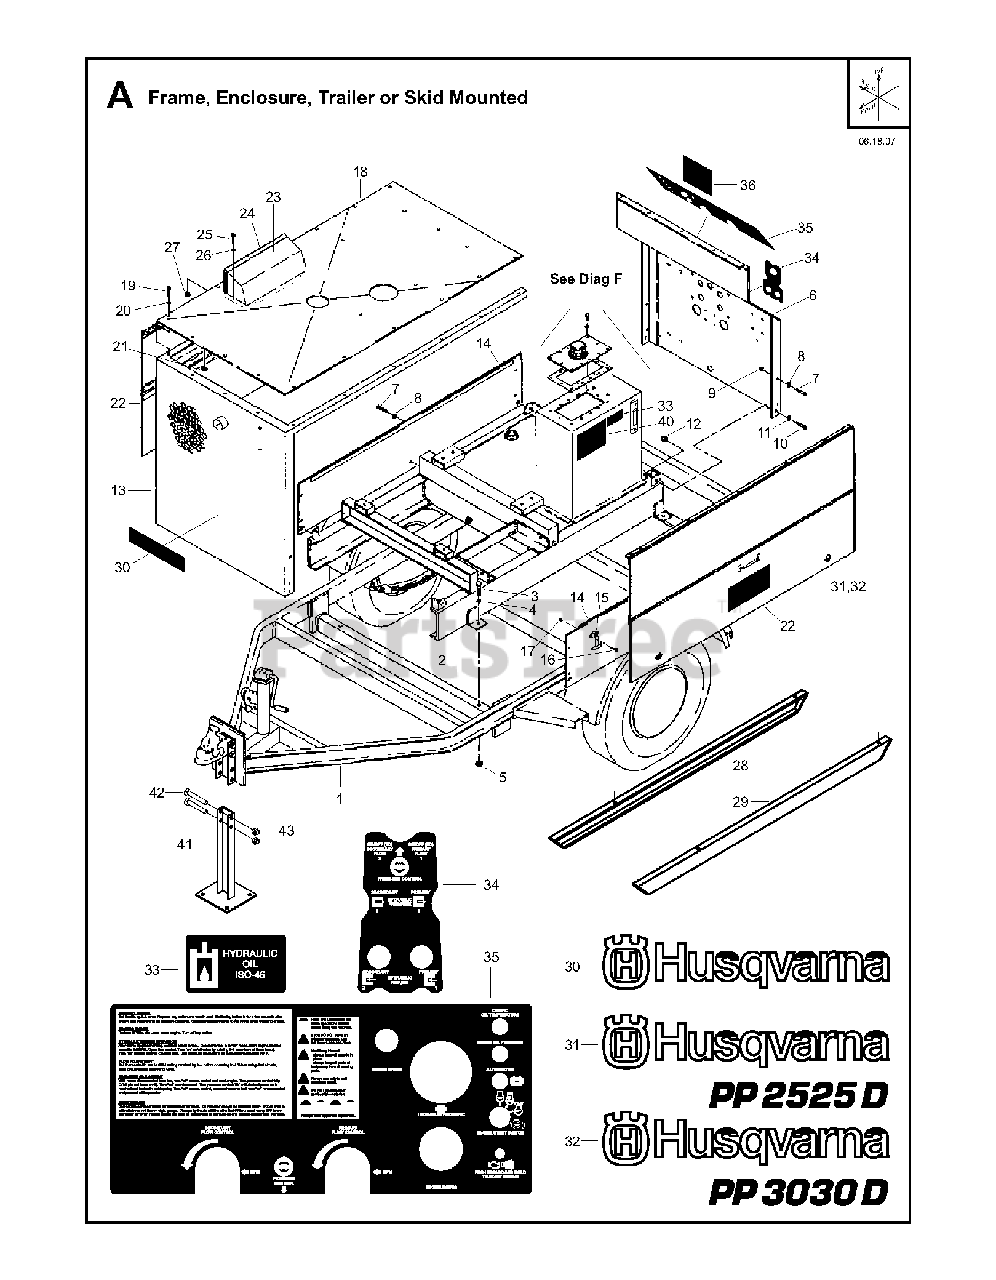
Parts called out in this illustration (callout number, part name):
1	FRAMESee Note Pos. 28-29
4	WASHERAlso used for 28-29
5	NUTAlso used for 28-29
9	NUT
12	NUT
17	NUT
20	WASHER 1/4 SAE
21	NUT
26	WASHER 1/4 SAE
27	NUT
29	SUPPORTUsed w/o Trailer
39	NUT 5/8-11 NYLOC GR 5 ZD
40	TBDDecal, Deutz Engine, Supplied By Deutz
